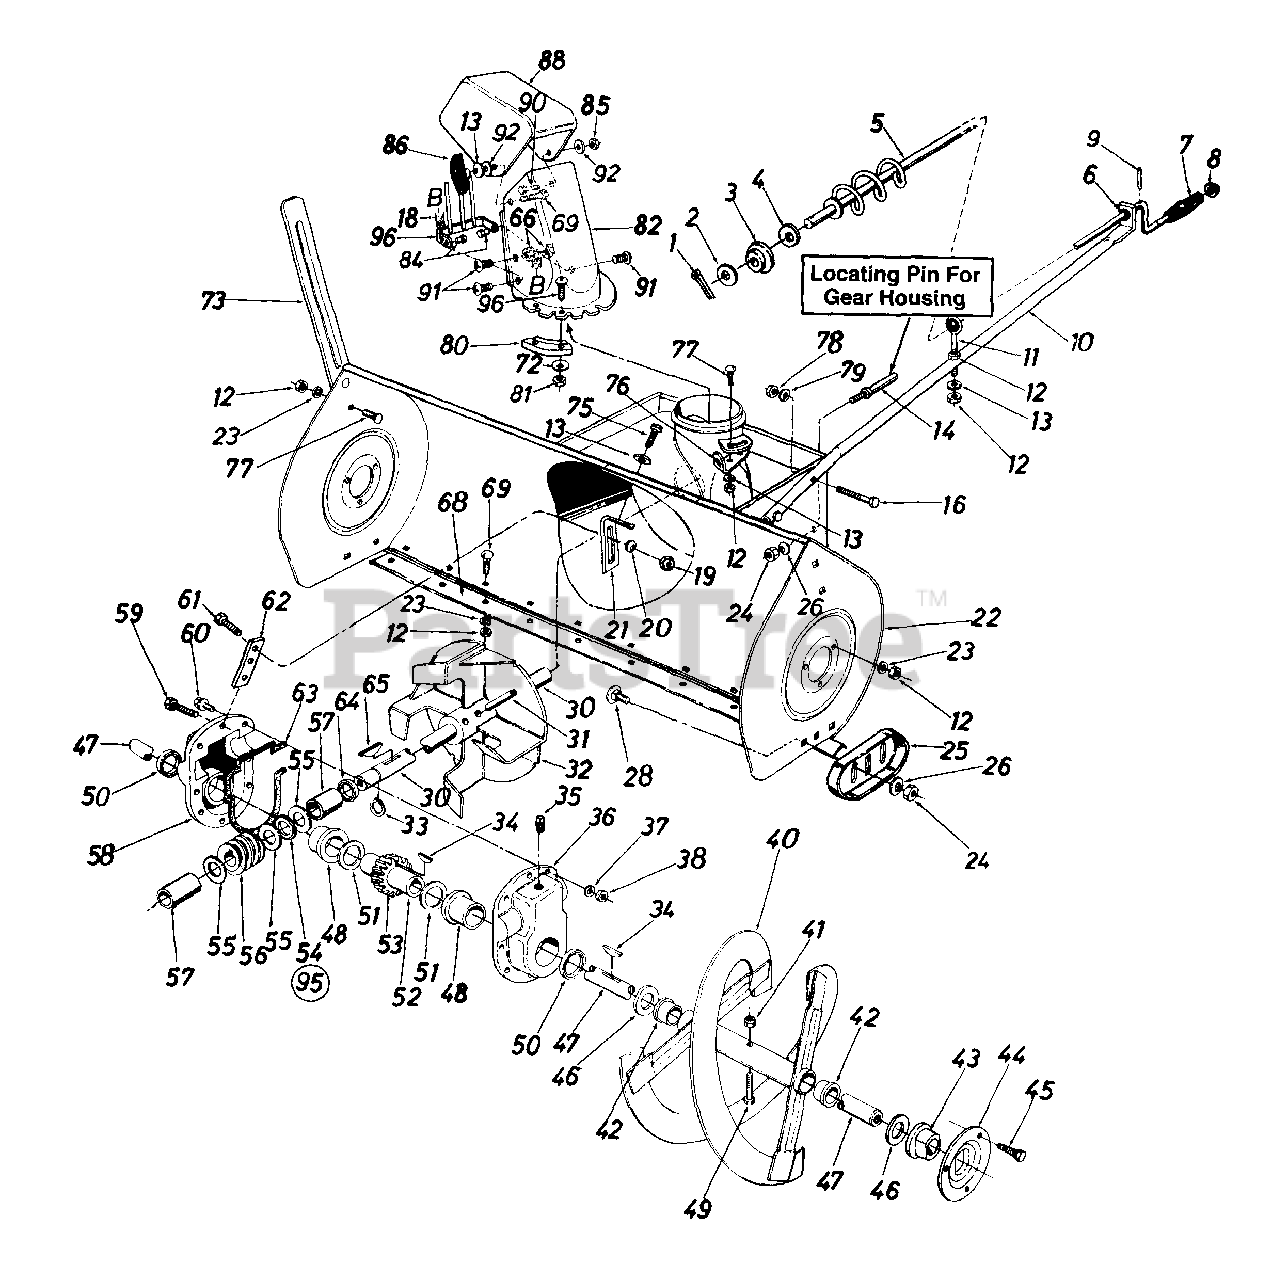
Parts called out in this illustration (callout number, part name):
1	Cotter Pin 3/32" x .75"
2	Fl-Wash. .385" I.D. x .62" O.D. x .06"
3	Plastic Bushing .380" I.D.
4	Fl-Wash. .385" I.D. x .62" O.D. x .06"
5	Chute Crank Ass'y.
6	Plastic Bushing .38" I.D.
7	Knob - Black
8	Cap Speed Nut 3/8" Rod
9	Spring Pin
10	Chute Crank Supporting Tube
11	Eyebolt Chute Crank Support
12	Hex Nut 5/16-18 Thd.
13	Bell-Wash. .345" I.D. x .88" O.D. x .06"
14	Belt Keeper Studs 3/8-16 x 2.75"
16	Hex Bolt 3/8-24 x 1.25" Lg.
18	Extension Spring
19	Hex Nut 1/4-28 Thd.
20	Bell-Wash. .25" I.D. x .88" O.D. x .062"
21	Gear Hsg. Support Brkt.
22	45" Snow Thrower Hsg. Ass'y.
23	L-Wash. 5/16" I.D.
24	Hex Jam Nut 3/8-16 Thd.
25	Reversible Slide Shoe
26	Bell-Wash. .4" I.D. x .88" O.D. x .06"
28	Carr. Bolt 3/8-16 x .62" Lg.
30	Blower Axle 14.75" Lg.
31	Spr. Spiral Pin - H.D.
32	Blower Fan Ass'y.
33	Snap Ring for .875" Dia. Shaft
34	#91 Woodruff Key 1/4" x 3/4" Dia.
35	Plastic Vented Plug 1/4-18 Pipe Thd.
36	Gear Hsg. Half - L.H.
37	Shakeproof Spr. Wash.
38	Hex Ins. L-Nut 5/16-18 Thd.
41	Hex Ins. L-Nut 5/16-18 Thd.
42	Flange Bearing
43	Flange Bearing w/Flats
44	Bearing Housing
45	Hex Sems Bolt 5/16-18 x .75" Lg.
46	Fl-Wash.
47	Spiral Axle
48	Flange Bearing
49	Shear Bolt 5/16-18 x 1.75
50	Oil Seal 1.5" I.D. Garlock
51	Fl-Wash. 1.5" I.D. x 2" O.D. x .03"
52	Worm Gear Shaft
53	Worm Wheel - L.H. Double Thd.
54	Thrust Brg. .88" I.D. x 1.44" O.D. x .078"
55	Fl-Wash. .88" I.D. x 1.4" O.D. x .125"
56	Worm Gear - L.H. Double Thd.
57	Sleeve Brg. .875" I.D.
58	Gear Hsg. Half - R.H.
59	Hex Bolt 5/16-18 x 1.25" Lg.
60	Hex Bolt 5/16 x 1" Lg.
61	Hex Bolt 1/4-28 x .75" Lg.
62	Gear Hsg. Support Plate
63	Rubber Gasket
64	Oil Seal for .875" I.D. Garlock
65	#9 Hi-Pro Key 3/16" x 3/4" Dia. - H.T.
66	Hex L-Nut 1/4-20 Thd.
68	Shave Plate
69	Carr-Bolt 5/16-18 x 1" Lg.
72	Fl-Wash. .281" I.D. x .5" O.D. x .063"
73	Guide Blade
75	Hex AB-Tap Scr. 5/16 x .75" Lg.
76	Chute Crank Brkt.
77	Carr. Bolt 5/16-18 x .75" Lg.
78	Hex Nut 3/8-24 Thd.
79	L-Wash. 3/8" I.D.
80	Chute Flange Keeper
81	Hex L-Nut 1/4-20 Thd.
82	Lower Chute
84	Shld. Nut 1/4-20 Thd.
85	Hex L-Nut 5/16-18 Thd.
86	Hand Knob
88	Upper Chute
90	Truss Mach. Scr. 5/16-18 x .75" Lg.
91	Truss Mach. Scr. 1/4-20 x .5" Lg.
92	Fl-Wash. .344" I.D. x 1.125" O.D. x .125"
95	Gear Box Ass'y. Complete
96	Truss Mach. Scr. 1/4-20 x 3/4" Lg.
